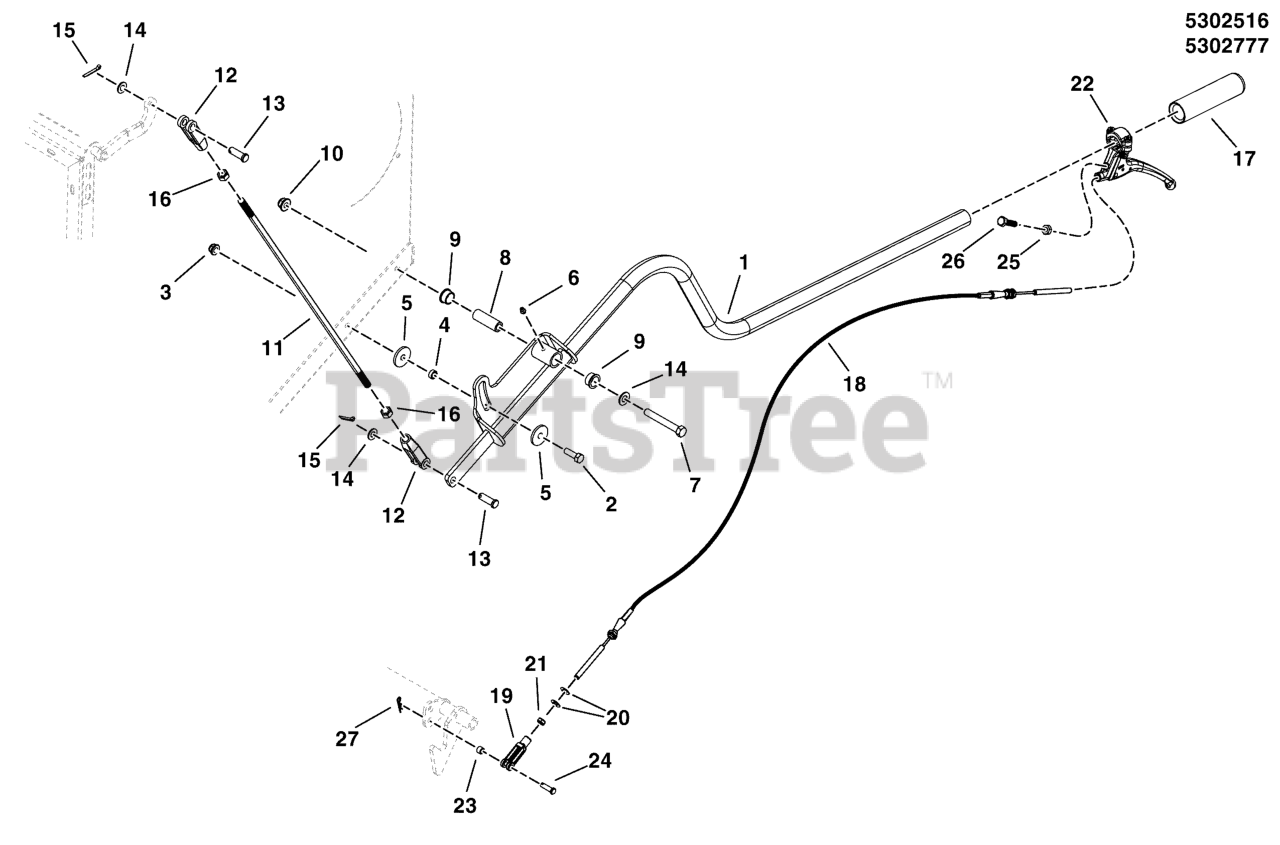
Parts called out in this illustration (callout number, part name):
2	BOLT, 5/16-18 X 1 GD5 YZ
3	NUT, 5/16-18 HEX NYLOCK FLANGE
4	SPACER-0.328ID 0.497OD 0.218LG PM YEL
5	WASHER, .34 X 1.25 X 10 GA
6	GREASE FITTING, PRESS, SHORT
7	BOLT, 3/8-16 X 2-3/4" GD5 CZ
8	SPACER-0.390ID 0.625OD 1.85 LG HARDENED
9	BUSHING-0.628IDX0.751ODX0.400LG PWDR MTL
10	NUT, 3/8-16 HEX NYLOCK FLANGE
11	ROD, GATE PULL, HOPPER
12	CLEVIS 3/8-24, PLASTIC
13	PIN, CLEVIS, 3/8 X 1-1/8, CZ
14	WASHER, 3/8 SAE
15	PIN, 3/32 X .750, COT, ZINC/CLEAR
16	NUT, 3/8-24 HEX JAM
17	GRIP, FOAM, .940" X 4.62" X .187"
18	CABLE, CONTROL, 57, GRASS COLLECTION
19	CLEVIS, 10-32 RH, CZ
20	WASHER, 5/16" SAE
21	NUT-HEX & WASHER ASMY 10-32 BLK (KEPS)
22	LEVER, RELEASE
23	SPACER, .25 X .37 X .25
24	CLEVIS PIN, 1/4 X 3/4, CZ
25	NUT, HEX, M8-1.0, CZ
26	BOLT, HEX, M8-1.0 X 30, CZ
27	PIN, HAIR, .0585 X 1-1/8, 1/4 EYE, YZ
